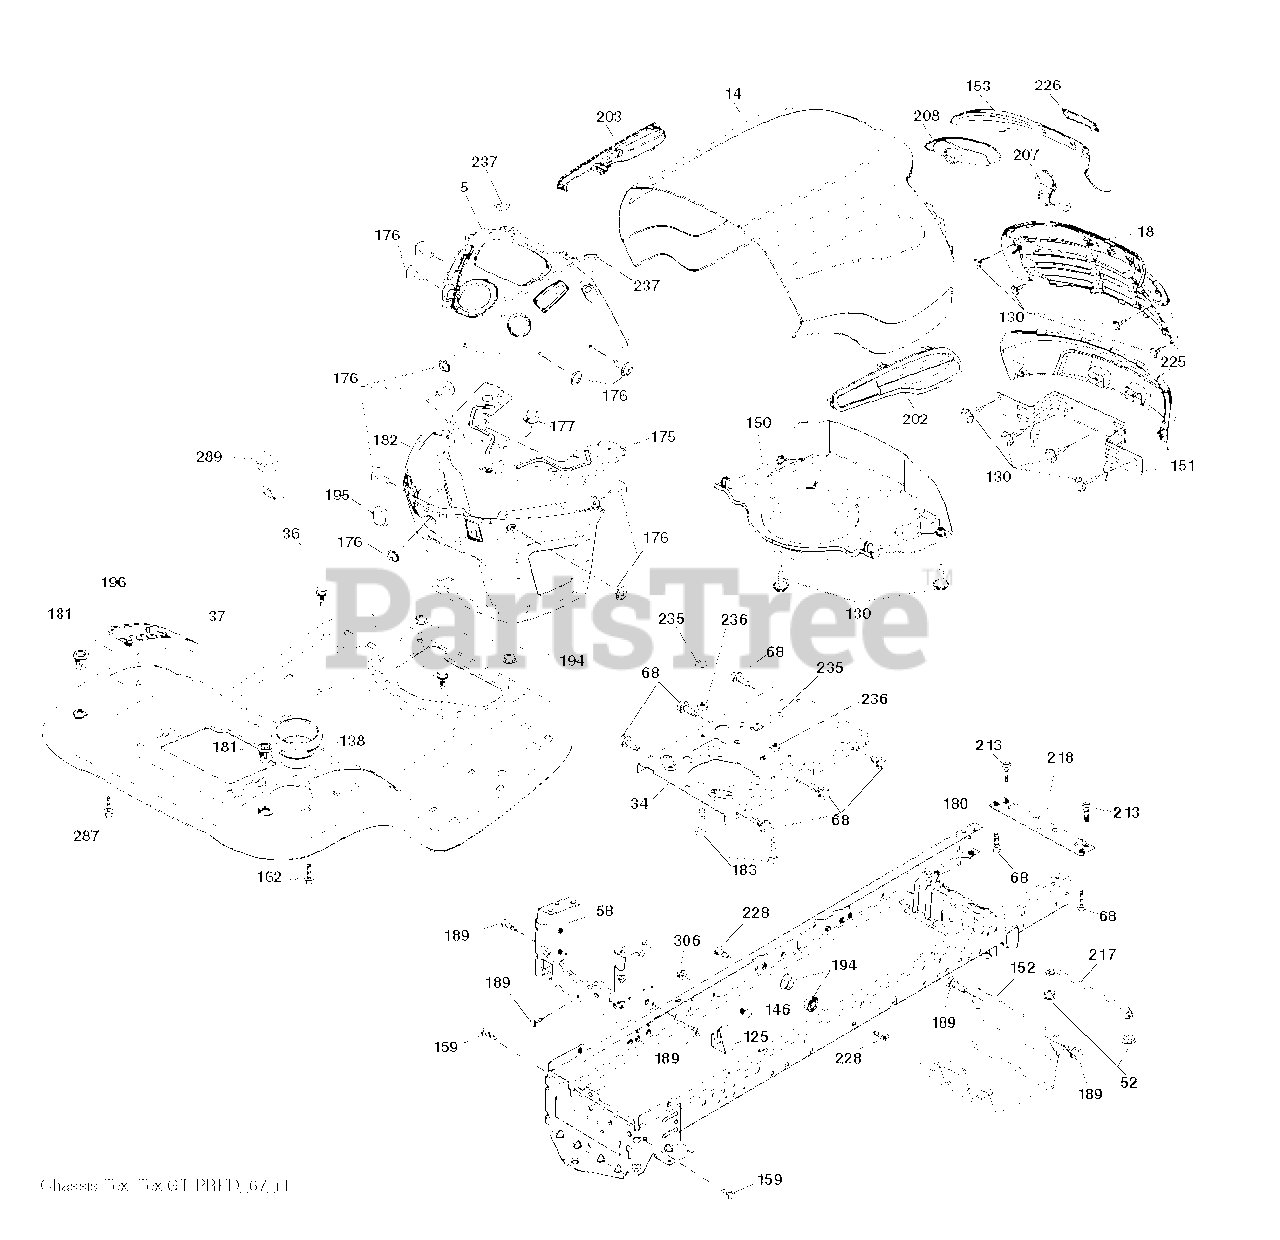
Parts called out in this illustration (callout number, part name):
36	SCREW 5/16"
52	LOCKNUT
58	DRAWBAR UPPER 2PC SMALL FENDER
68	SCREW LT
125	Fuel Line Clip
130	SCREW.#10 X 0.750.BOS THREAD
138	CUPHOLDER.TL.TEX.BLACK
146	BOLT.RDHD.SHT.SQNK.3
152	SHIELD BROWNING
159	SCREW, 3/8-16X3/4
162	SCREW.HI-LO.CONSOLE
175	PLATE.CROSSMEMBER.HUSQ
176	SCREW.#10-24X5/8.RN.QU
177	BUSHING,STEERING
180	CHASS.WLDMNT.TL.12GA/2P.48/54
181	FEND/FTRST.PCH.CPH.NFW
182	DASH.LOWER.COMMON.12V.ADAPTOR
183	BOLT.5/16-18X1-1/4 FULL THD
189	SCREW
194	NUT LOCK HEX FLANGE 5/16-18
195	PLUG.HOLE.DASH.LOWER.12V.BLK
196	CONSOLE.ASM.DECKLFT.BL/RBT.TLT
213	BOLT
217	ROD.PIVOT.HOOD
218	X-PIECE.HOOD.STOP.NON/
228	STUD.FASTNER.W/ANTI-ROTATE
235	SPACER FENDER
236	NUT.CENTERLOCK.5/16-
237	PLUG.MOUNT.CARGO.BLK
289	PLUG.N/CRUISE.COMMON.YT/GT.BLK
306	NUT LOCK FLG 3/8-16 UNC
